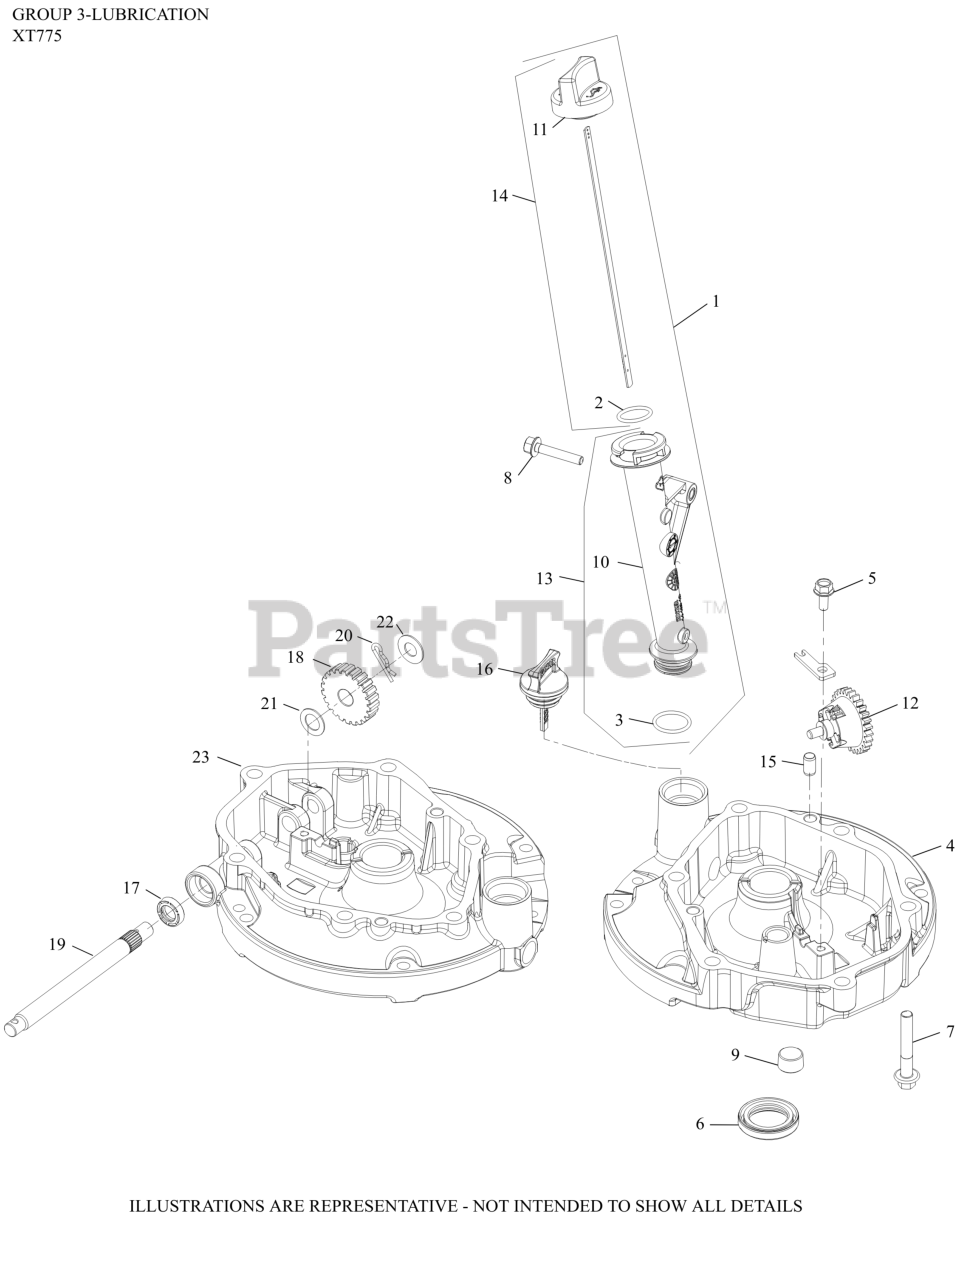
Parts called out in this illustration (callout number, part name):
1	KIT, DIPSTICK AND TUBE-(#1412320S)
1	TUBE ASSEMBLY OIL FILL
2	O-RING (CAP)
3	O-RING, OIL FILL TUBE
4	KIT, OIL PAN
7	SCREW, HEX FLANGE (M8)-USE 25 086 456-S
8	SCREW, HEX FLANGE (M6)-(#25086435S)
9	PLUG, PIPE (W/SEALANT)
12	GEAR ASSEMBLY, GOVERNOR
12	GOVERNOR ASSEMBLY-USE 17 310 08-S
13	TUBE ASSEMBLY, OIL FILL
14	CAP, DIPSTICK ASSEMBLY
15	PIN, DOWEL (8MM)
